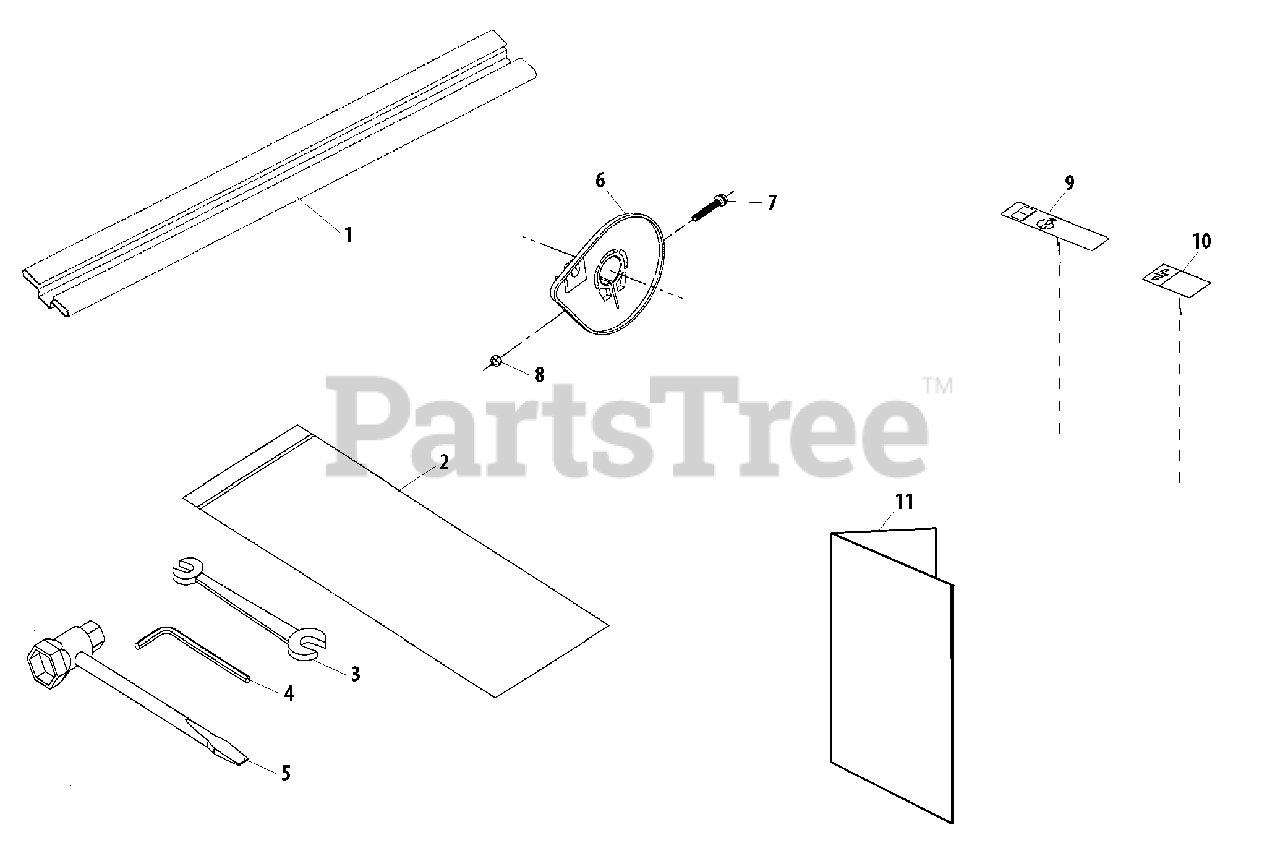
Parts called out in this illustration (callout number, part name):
1	SCABBARD
2	BAG, TOOL
3	SPANNER 8×10
4	WRENCH, ALLEN 4 MM
5	T-WRENCH 13×19 MM
6	GUARD, HAND
7	SCREW M5×30
8	NUT M5
9	LABEL, CAUTION
10	LABEL, HIGH VOLTAGE
11	OWNER'S MANUAL
